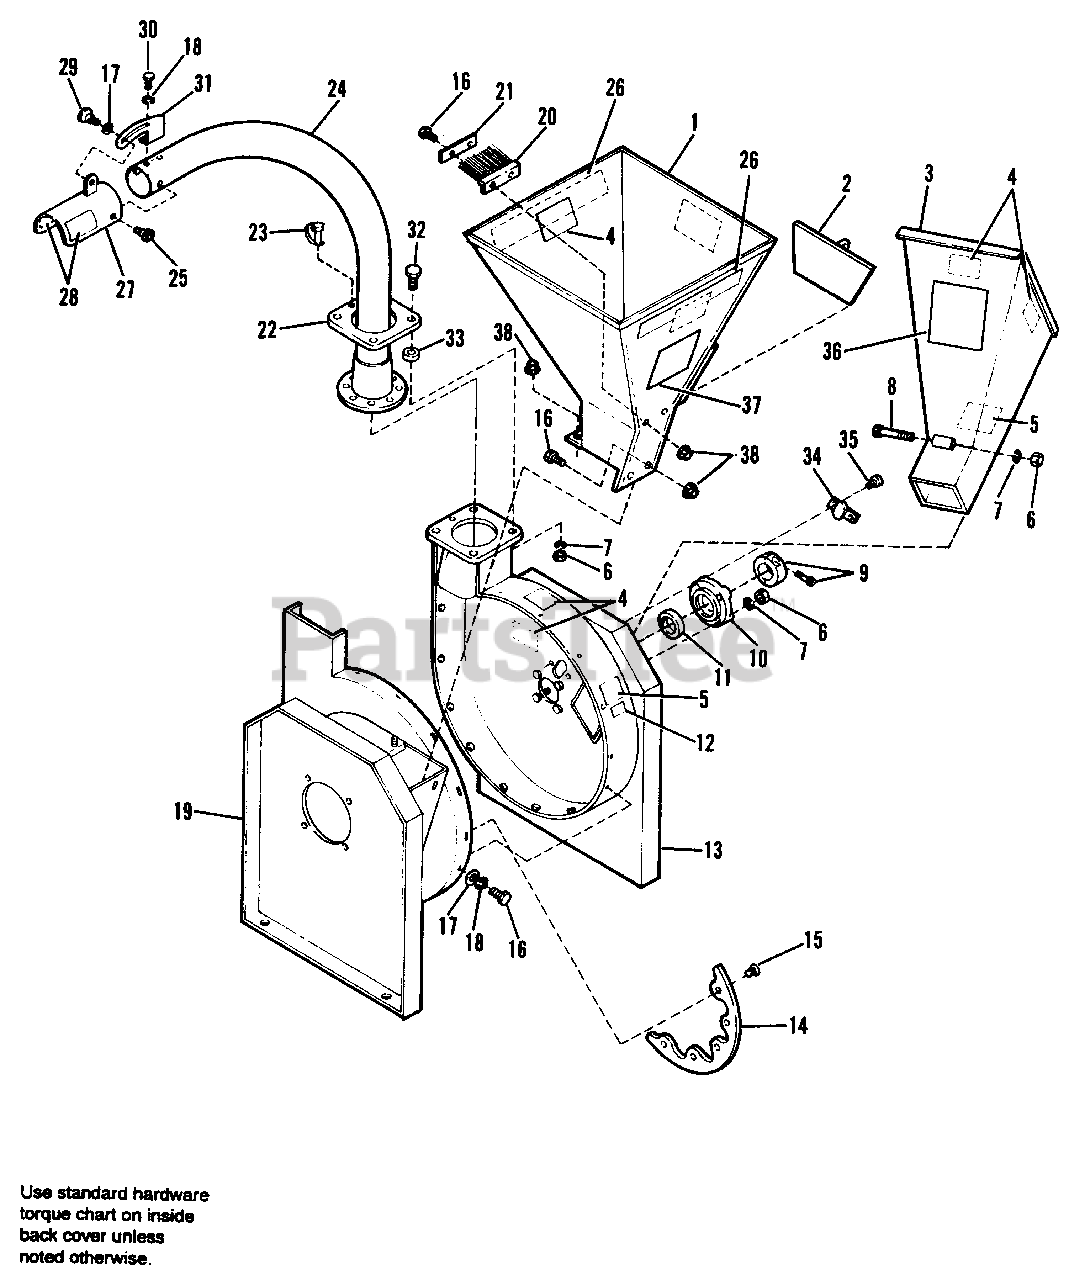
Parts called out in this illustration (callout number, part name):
1	HOPPER, Shredder, 20HP
1	HOPPER, Shredder, 23 HP
2	COVER PLATE, Vacuum, 20 HP
2	COVER PLATE, Vacuum, 23 HP
3	HOPPER, Chipper, 20 HP
3	HOPPER, Chipper, 23 HP
4	DECAL, Danger, Rotating Cutters
5	DECAL, Caution
6	NUT, Hex, 3/8-16
7	LOCKWASHER, 3/8
8	CAPSCREW, Socket Hd., 3/8-16 x 41/2
9	COLLAR, Lock
10	BEARING, w/RaceLock&SetScrews
11	SPACER, Bearing
12	PLATE, Serial No.
13	CHIPPER HOUSING, Mounting Side, 20 HP (PTO)
13	CHIPPER HOUSING, Mounting Side, 23 HP (PTO)
14	DEFLECTOR, 20 HP
14	DEFLECTOR, 23 HP
15	SCREW, Flat Hd., 5/16-18 x 5/8 (Apply Loctite)
16	CAPSCREW, 5/16-18 x 3/4, 23 HP
16	CAPSCREW, 5/16-18 x 3/4, 20 HP
17	WASHER, 5/16, 23 HP
17	WASHER, 5/16, 20 HP
18	LOCKWASHER, 5/16, 23 HP
18	LOCKWASHER, 5/16, 20 HP
19	CHIPPER HOUSING, Drive Side, 20 HP (PTO)
19	CHIPPER HOUSING, Drive Side, 23 HP (PTO)
19	CHIPPER HOUSING Drive Side, 20 HP (Trailer)
19	CHIPPER HOUSING Drive Side, 23 HP (Trailer)
20	GUARD, Hopper, 7-1/2" Long (20 HP)
20	GUARD, Hopper, 8-1/2" Long (23 HP)
21	STRAP, 23 HP
21	STRAP, 20 HP
22	CLAMP, Discharge
24	DISCHARGE TUBE, 20 HP
24	DISCHARGE TUBE, 23 HP
25	BOLT, Shoulder, Socket Hd., 5/16-18 x 1/2
26	DECAL, Simplicity
26	DECAL, Baker, 2020
27	DEFLECTOR, Discharge Tube
28	DECAL, Warning
30	CAPSCREW, 5/16-18 x 1/2
31	BRACKET, Deflector Adjusting
32	CAPSCREW, 3/8 16 x 1-1/2
33	SPACER, Discharge Tube
34	PLATE, Access
35	TAPTITE SCREW, 5/16-18 x 5/8
36	DECAL, Chipper Warning
37	DECAL, Shredder Warning
38	NUT, Hex, Flange, Lock, 5/16-18
